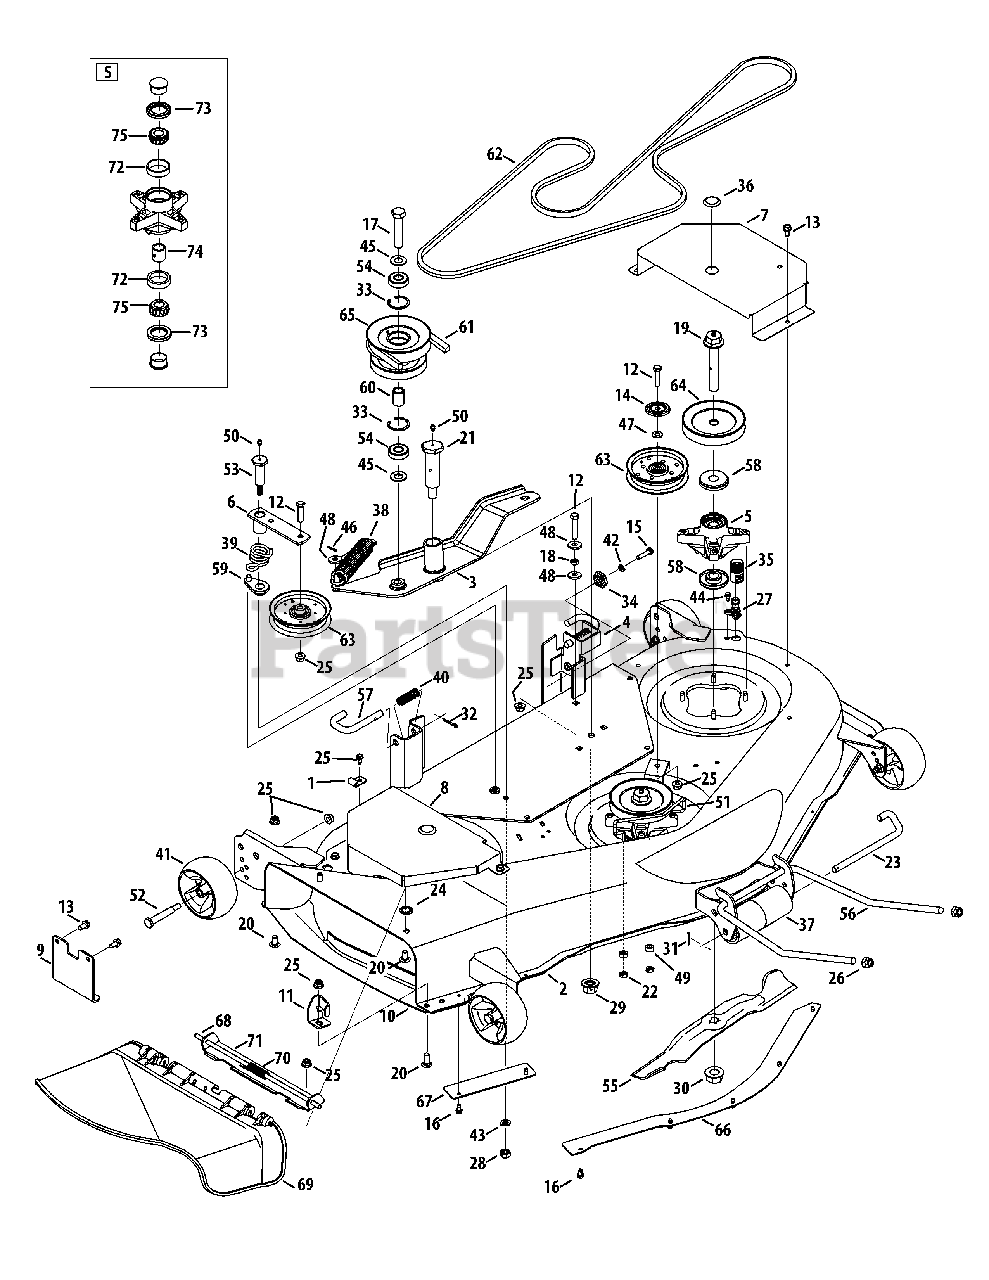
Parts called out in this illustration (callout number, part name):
1	Hook Retainer Bracket
4	Hanger Adjustment Bracket
5	Spindle Assembly
7	LH Spindle Shield
8	RH Spindle Shield
9	Up-Stop Bracket
11	Chute Deflector Stop
12	Hex Screw, 3/8 x 16 x 1.75
13	Hex Washer Screw, 5/16-18 x .750
14	Pulley Cap
15	Hex Screw, 5/16-18 x 1.25
16	Hex Washer Screw, 1/4-20 x .500
17	Hex Screw, 5/8-18 x 3.00
18	Jam Nut, 3/8 x 16
19	Spindle Bolt, 3/4-16 x 4.25
20	Carriage Bolt, 3/8-16 x 1.00
21	Shoulder Screw, 1.0 x 3.00
22	Hex Lock Nut, 1/4-20
23	Roller Pin, 1/2 x 7.31
24	Push Nut, 3/8
25	Flange Lock Nut, 3/8-16
26	Flex Lock Nut, 1/2-13
27	Hex Nut, M16-1.5
28	Hex Nut, 7/16-14
29	Flange Lock Nut, 5/8-18
30	Flange Lock Nut, 3/4-16
31	Cotter Pin, 3/32 x 1.25
32	Cotter Pin, 5/32 x 1.25
33	Retainer Ring
34	Deck Adjustment Gear
35	Water Nozzle Adapter
36	Button Plug
37	Front Roller
38	Extension Spring, 1.25 x 6.9
39	Idler Torsion Spring, 1.10 x 1.3
40	Compression Spring, .66 x 1.8
41	Deck Wheel, 5.0
42	Lock Washer, 5/16
43	Lock Washer, 7/16
44	Lock Washer, 5/8
45	Flat Washer, .65 x 1.25 x .075
46	Cotter Pin, 3/32 x .750
47	Flat Washer, .406 x .812 x .051
48	Falt Washer, .385 x 1.00 x .135
49	Deck Water Nozzle
50	Drive Lube Fitting, 3/16
51	Belt Drive Guard
52	Shoulder Screw, 1/2 x 2.50
53	Shoulder Screw, 7/16-14 x .687 x 2.443
54	Ball Bearing, .625 x 40 x 12
55	2-in1 Blade
56	Front Lift Rod
57	Mower Support Pin
58	Spindle Spacer
59	Spring Retainer
60	Spacer, .88 x .635 x 1.25
62	Deck Belt
63	Idler Pulley
64	Spindle Pulley
65	Double Pulley
68	Hinge Pin, .3175 x 14.06
69	Chute Deflector
70	Torsion Spring, .44 x 2.0
71	Chute Bracket
72	Bearing Cup, .750
74	Bearing Spacer, .78 x 1.0 x 1.0425
75	Cone Bearing, .750
76	Spacer, .256 x .500 x .240
